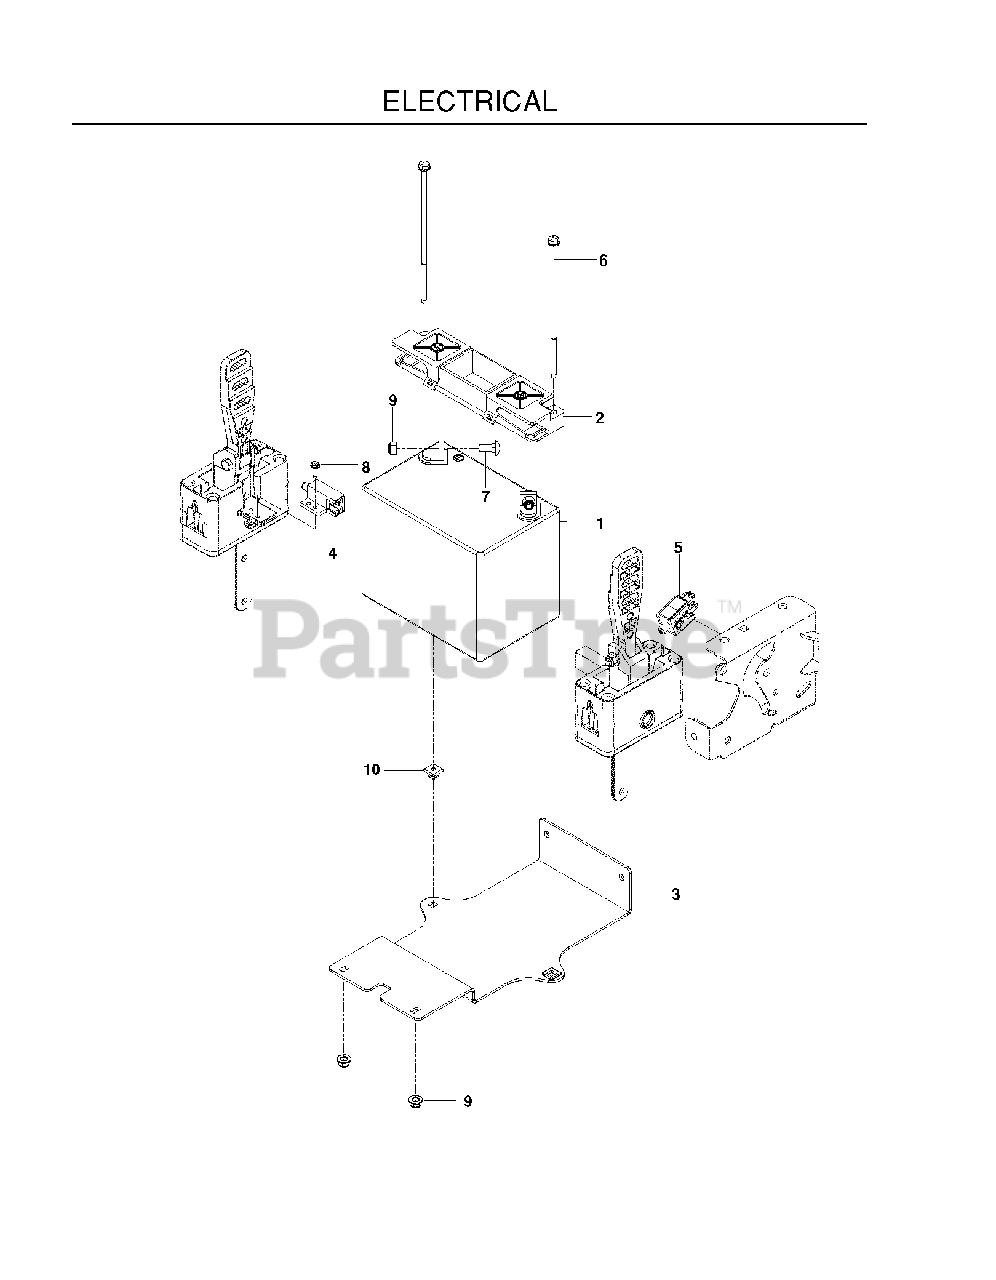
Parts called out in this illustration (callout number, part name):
1	BATTERY, 12 V 330 AMP
2	BATTERY HOLD DOWN
3	PLATE, BATTERY, BLACK
4	SWITCH, INTERLOCK
5	SWITCH, BRAKE 3P
6	Bolt, 1/4-20 X 7.5
7	BOLT 5/16C X 3/4" CARRIAGE
8	SCREW #10 X 1/2 SELF TAPPING
9	5/16-18 NYLOC FLANGE NUT
10	PUSH NUT-NYLON
